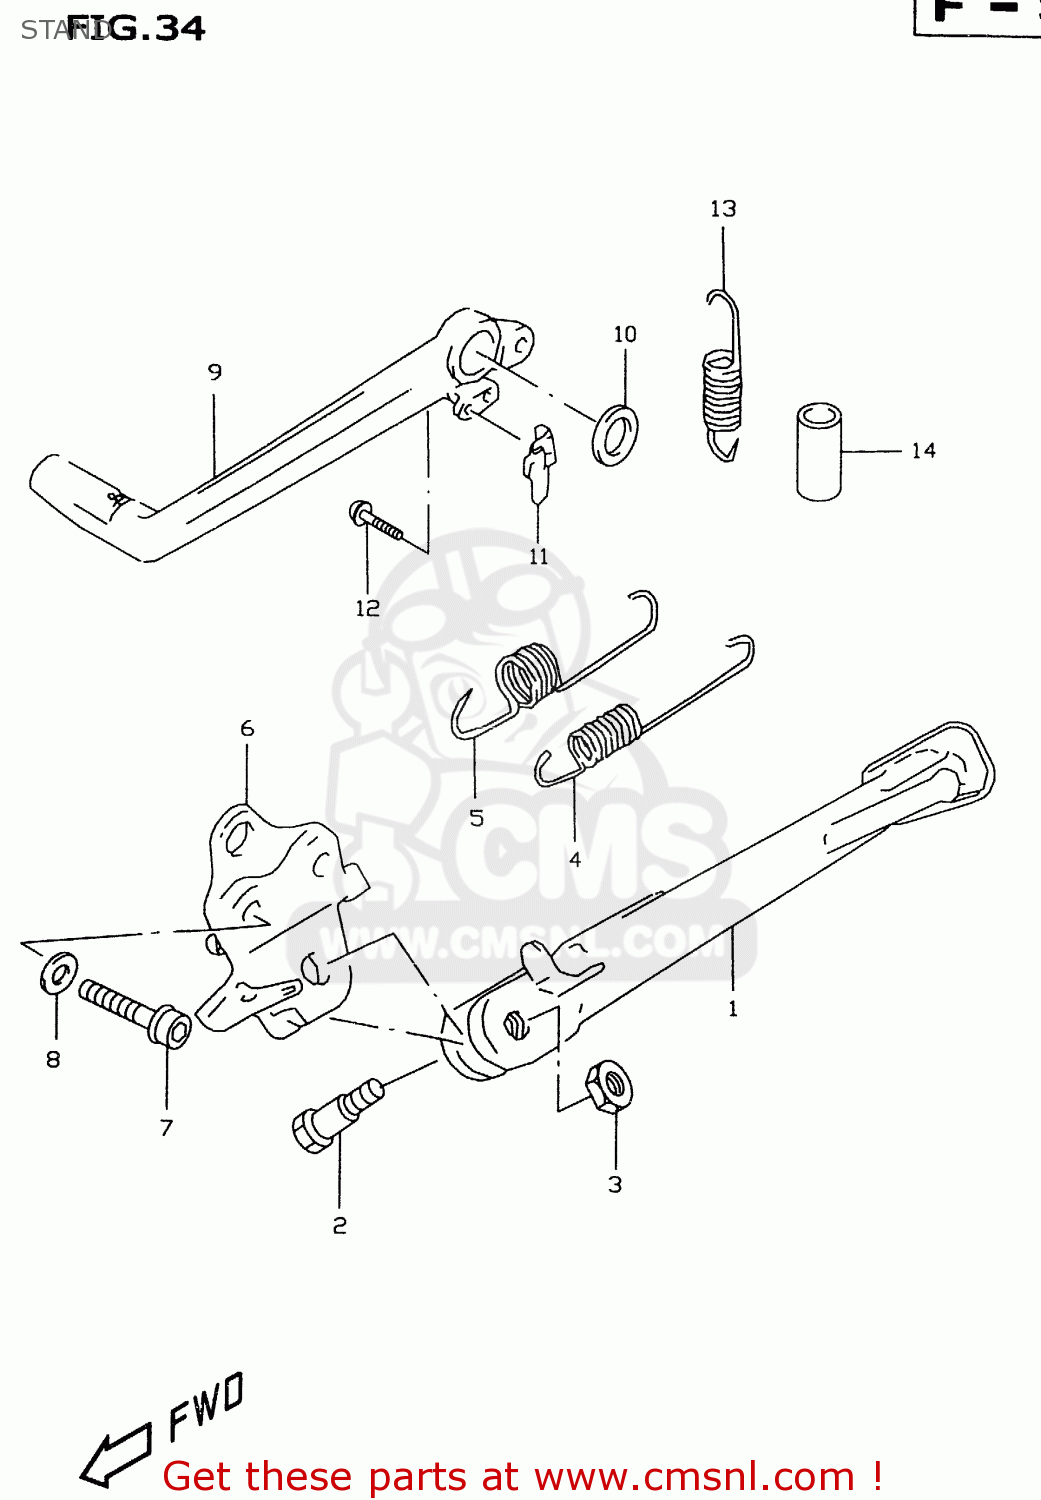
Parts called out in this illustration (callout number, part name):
1	STAND,PROP
2	BOLT(10X34)
3	NUT
4	SPRING
5	SPRING
6	BRACKET,PROP STAND
7	BOLT
8	LOCK WASHER
9	PEDAL,BRAKE
10	WASHER(18X24X1)
11	HOOK,RETURN SPRING
12	SCREW
13	SPRING
14	TUBE,BRAKE SPRING GUIDE
